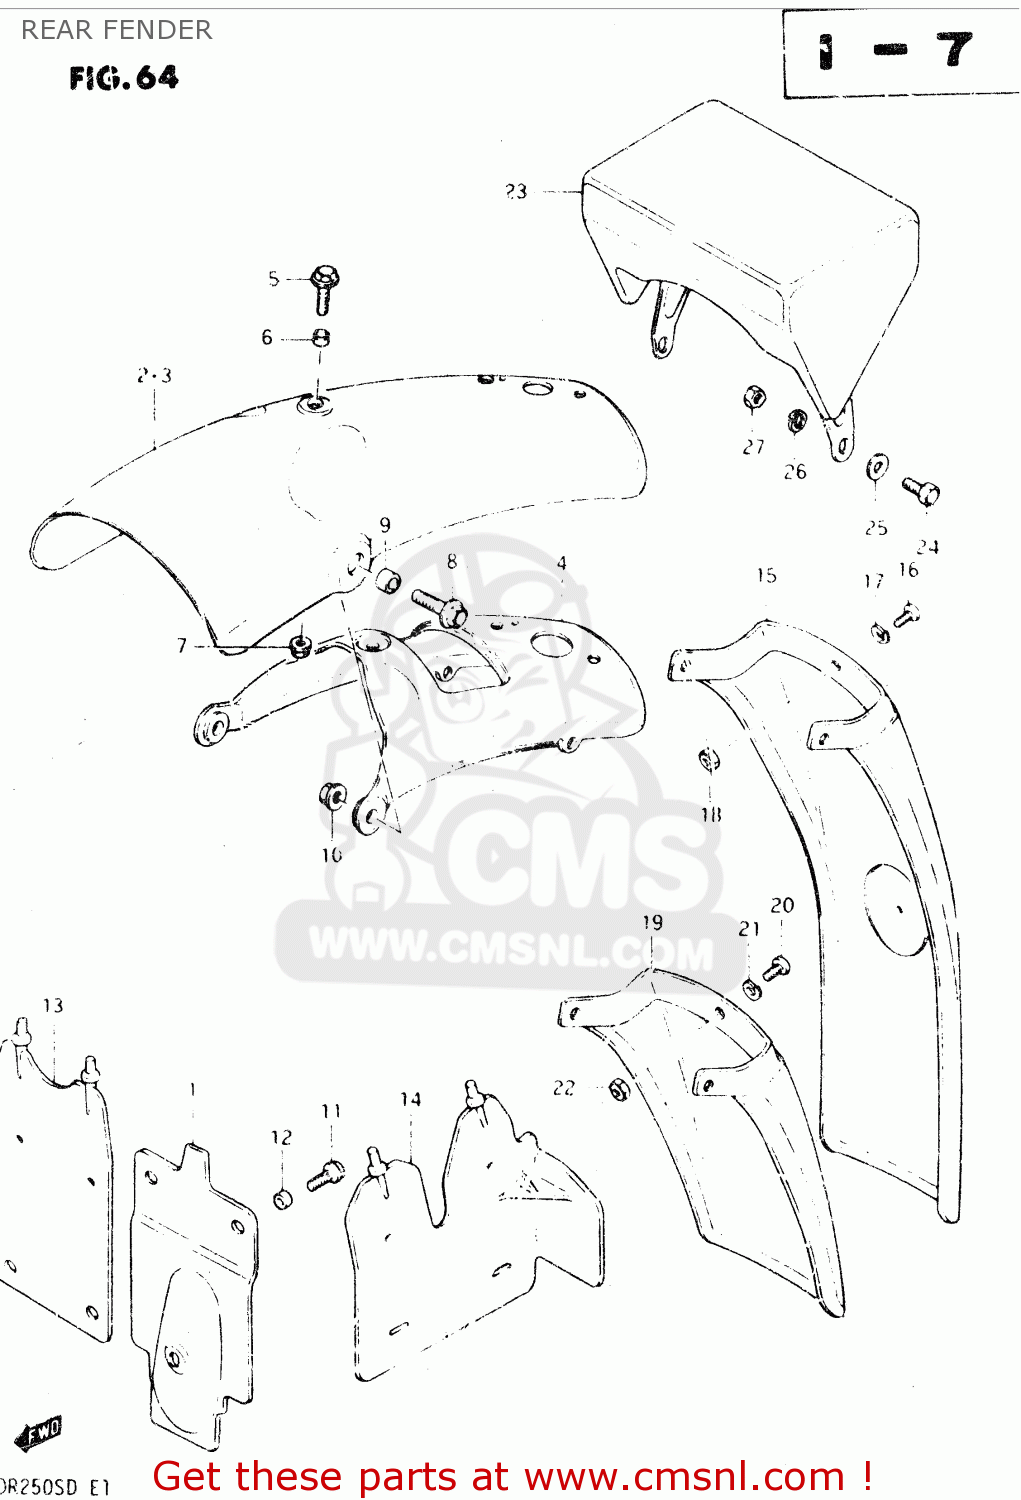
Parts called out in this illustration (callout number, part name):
1	REAR FENDER,FRONT
2	FENDER, REAR (BLUE)
3	FENDER, REAR (BLUE)
4	REINFORCEMENT
5	BOLT,REAR
6	SPACER
7	NUT
8	BOLT
9	SPACER(8.2X14X4.5)
10	NUT
11	SCREW, FRONT
12	SPACER
13	MUD GUARD,REAR FENDER
14	MUD GUARD
15	EXTENSION, REAR FENDER
16	SCREW
17	LOCK WASHER
18	NUT
19	EXTENSION, REAR FENDER
20	SCREW
21	LOCK WASHER
22	NUT
23	BAG
24	BOLT
25	WASHER
26	LOCK WASHER
27	NUT
